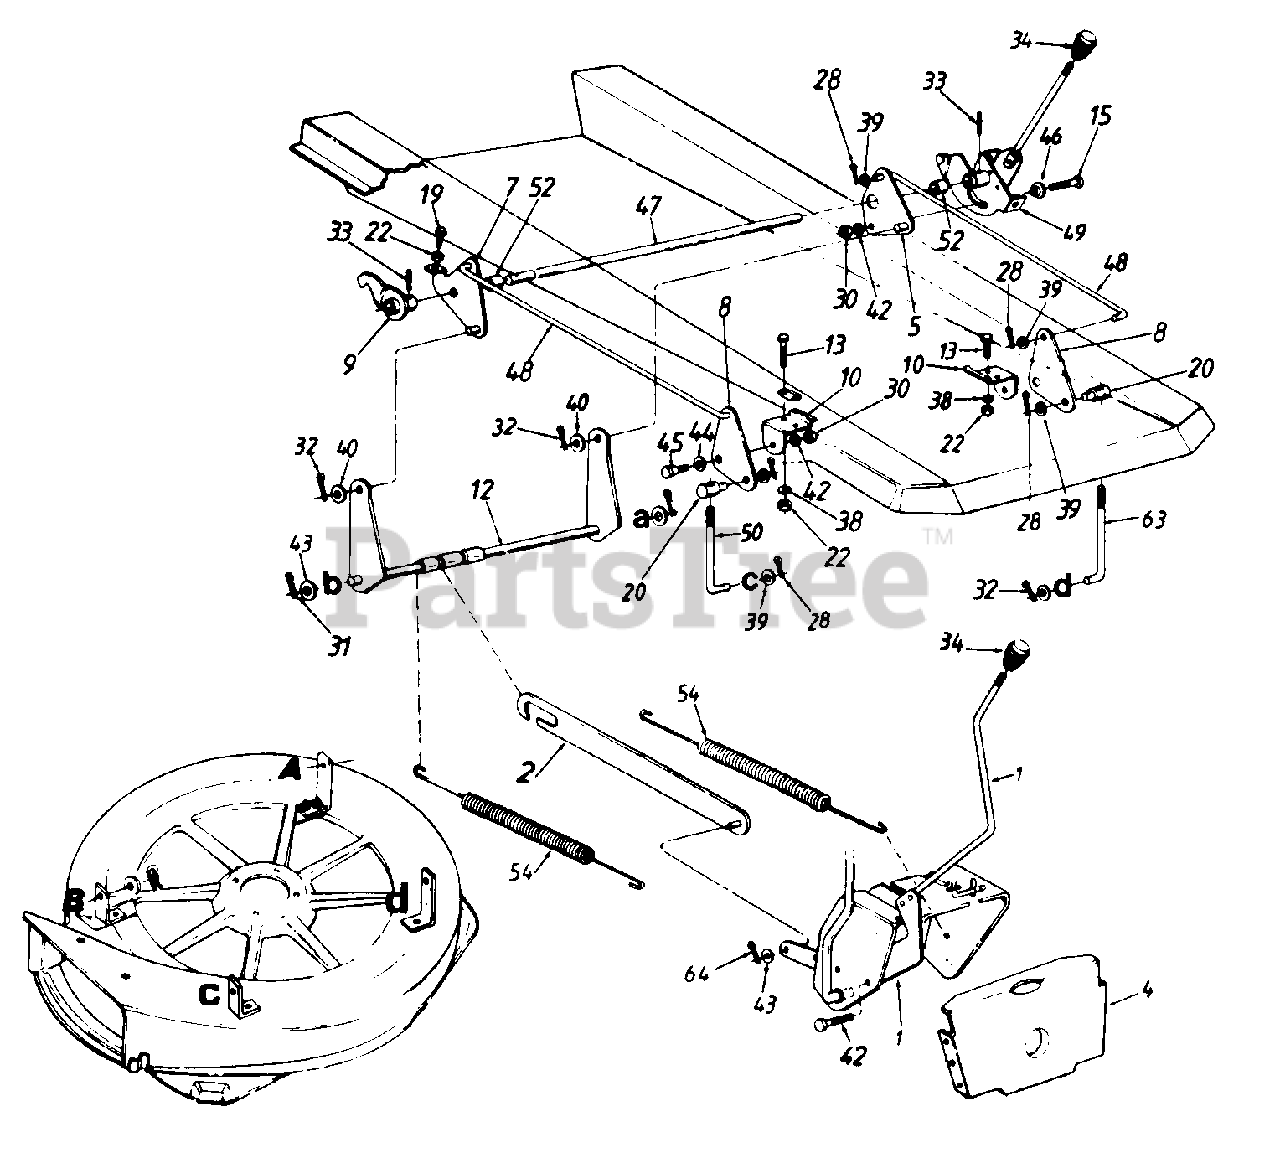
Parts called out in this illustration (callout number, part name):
7	Deck Lift Brkt. Ass'y.
8	Deck Lift Bracket
9	Deck Lift Float Brkt Ass'y.
10	Deck Lift Pivot Brkt.
15	Hex Bolt 3/8-16 x 1" Lg.
19	Hex Wash.-Tap Scr. 5/16-18 x 1.25" Lg.
20	Ferrule
22	Hex Nut 5/16-18 Thd.
28	Cotter Pin 3/32" Dia.
30	Hex Nut 3/8-16 Thd.
31	Internal Cot. Pin 1/2" Dia.
32	Int. Cot. Pins 3/8" Dia.
33	Spring Pin Spir. 1/4" Dia.
34	Knob
38	L-Wash 5/16" I.D.
39	Fl-Wash. .385 I.D. x .62
40	Fl-Wash. .635 I.D. x 1.12
42	L-Wash. 3/8" I.D.
43	Fl-Wash. .385 I.D. x .87 O.D.
44	Spring Washer .530 I.D.
45	Shld. Bolt .500" Dia. x .215"
46	Shld. Spacer .625" I.D.
47	Rear Hgt. Adj. Shaft
50	J-Bolt 3/8-24 x 5.25" Lg.
52	Spacer .885 I.D.
54	Ext. Spring 13.25" Lg.
63	J-Bolt 3/8-24 x 5.4" Lg.
64	Cotter Pin 1/8" Dia.
